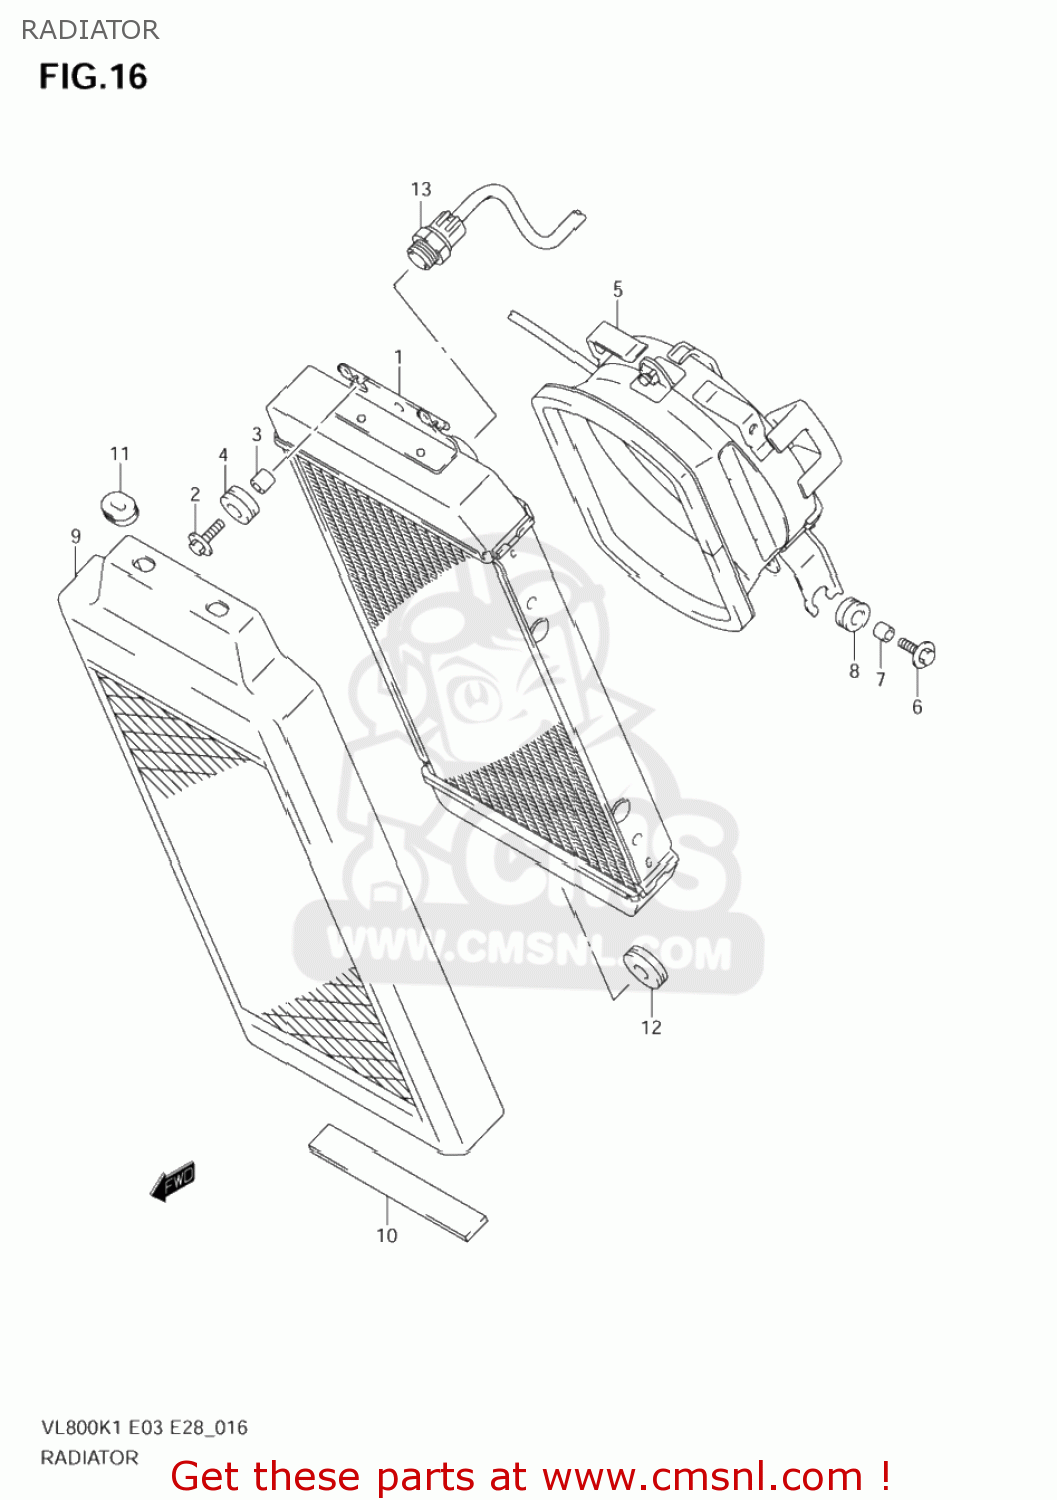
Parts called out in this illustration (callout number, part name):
1	RADIATOR ASSY,WATER
2	BOLT(6X20)
3	SPACER(6.5X10X10)
4	CUSHION
5	FAN ASSY,RADIA
6	BOLT(6X20)
7	SPACER(6.5X10X10)
8	CUSHION
9	COVER,RADIATOR
10	CUSHION,RADIATOR COVER INNER
11	CUSHION
12	CUSHION
13	SWITCH ASSY,WA
